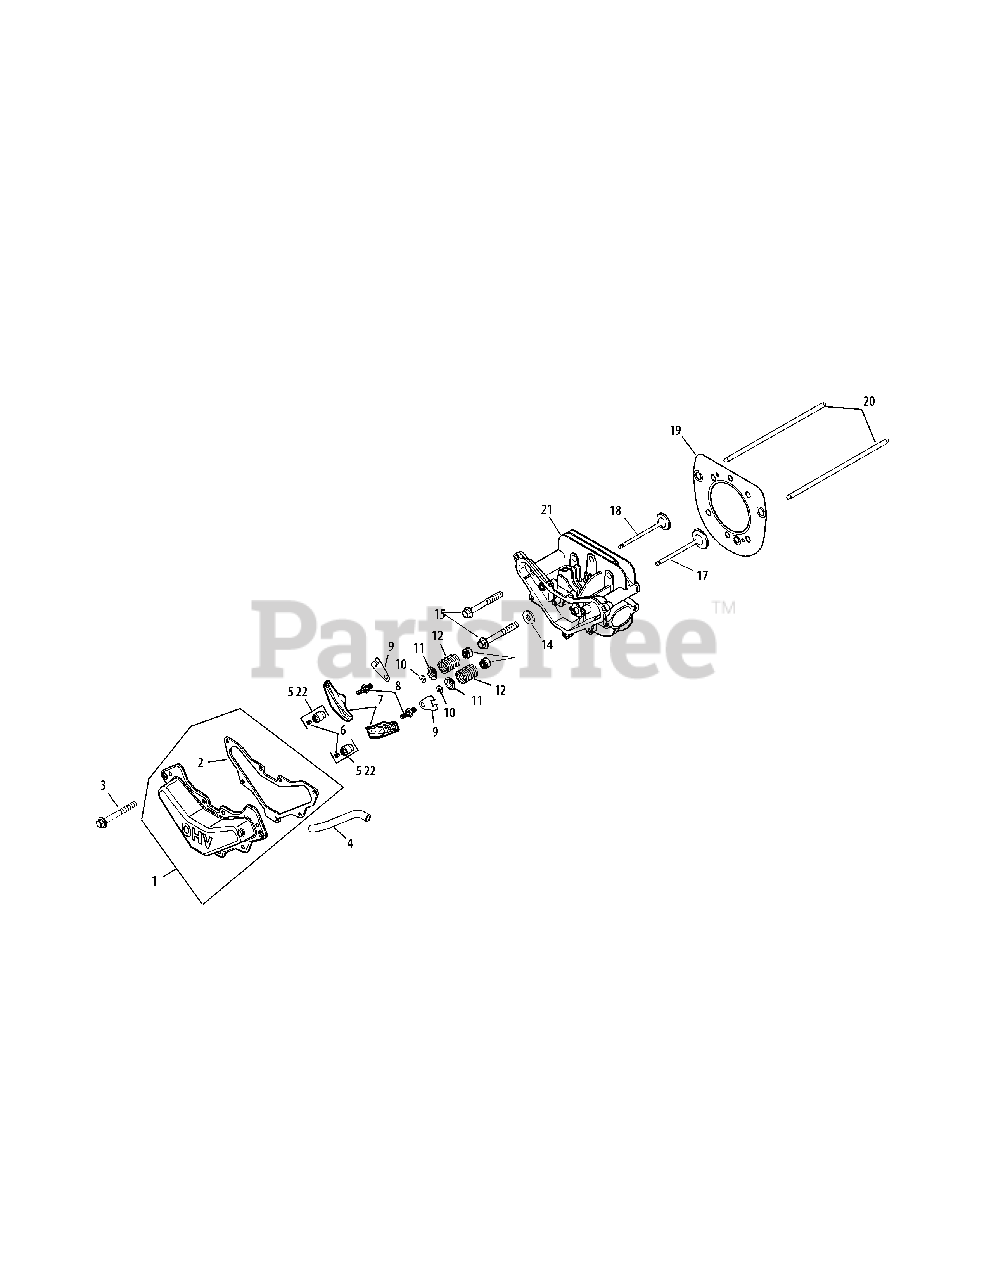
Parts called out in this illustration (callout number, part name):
1	Valve Cover Kit (Incl. 2)
2	Valve Cover Gasket
3	Flange. Screw, M6 X 1.0 X 20
4	Breather Hose
5	Rocker Pivot Assembly (Incl. 6)
9	Push Rod Guide Plate
10	Retainer Lock
11	Valve Spring Cap
14	Flat Washer, 13/32
15	Flange Screw, M10 X 1.5 X 80
17	Exhaust Valve
19	Cylinder Head Gasket Kit
20	Rod, Push
21	Kit, Cylinder Head (Incl. 28 & 29)
22	Kit Pivot, Rocker Arm (Incl. 6)
